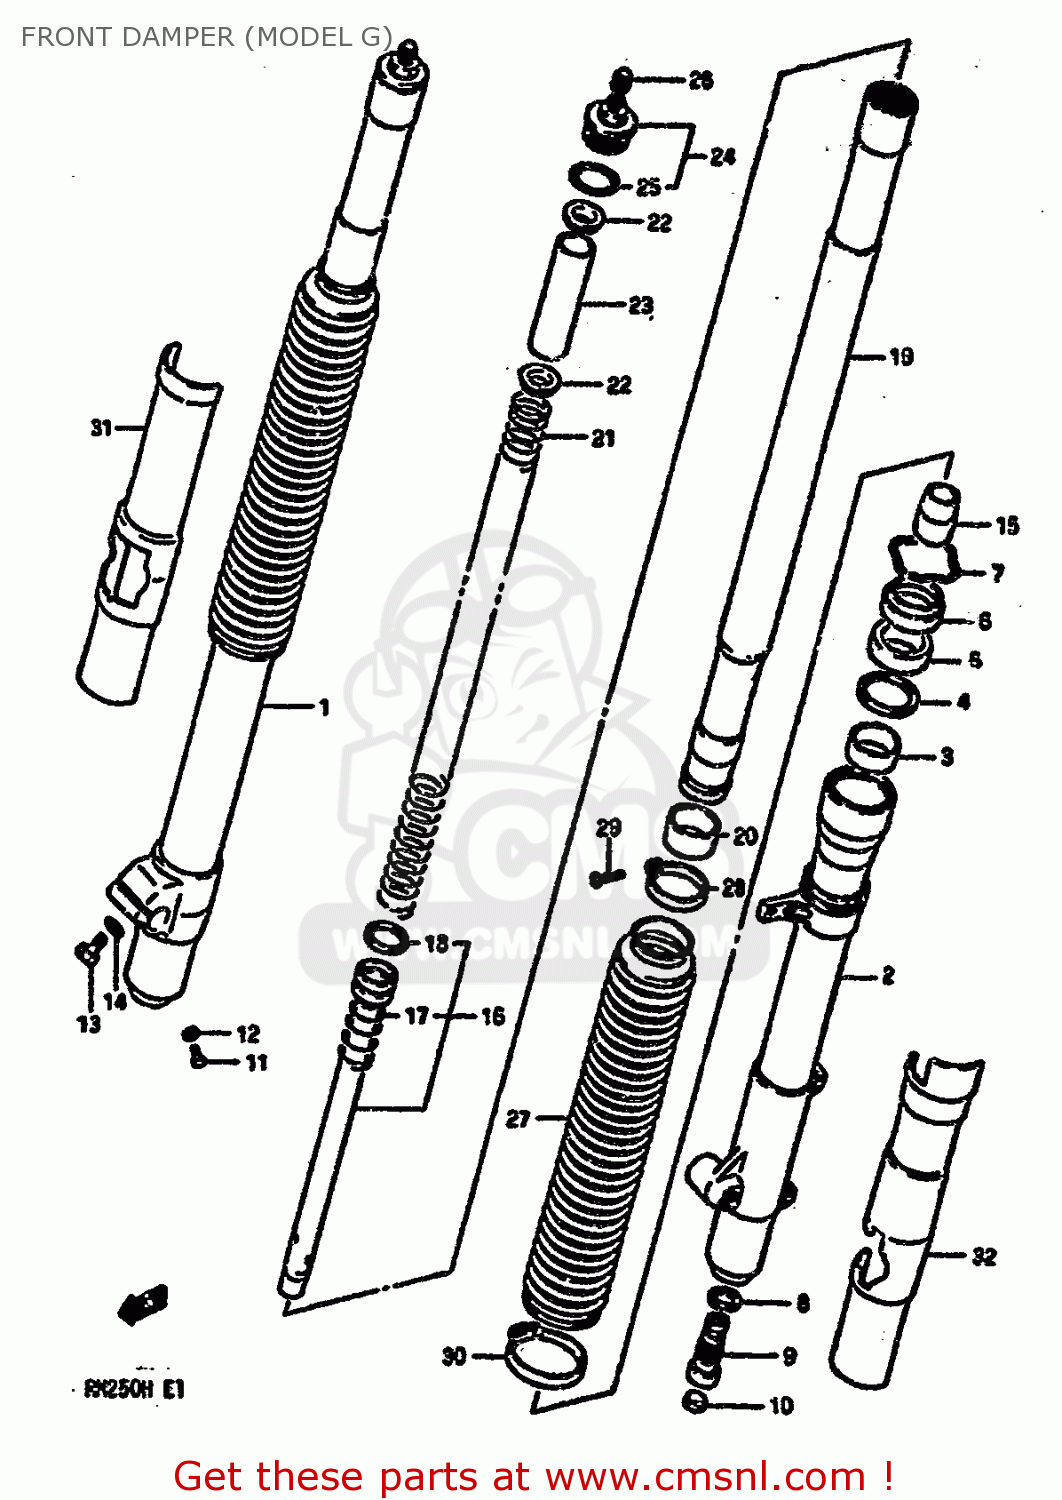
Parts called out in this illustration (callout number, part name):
1	TUBE,OUTER,RIGHT
2	TUBE,OUTER,LEFT
3	METAL,SLIDE
4	WASHER
5	SEAL,OIL
6	SEAL,DUST
7	RING,STOPPER
8	GASKET,FORK CYLINDER
9	VALVE,DF
10	CAP,FRONT FORK DF
11	SCREW 4X6
12	GASKET,DRAIN,PLUG (NAS)
13	BOLT
14	WASHER,LOCK,8.
15	PIECE,FRONT FORK OIL LOCK
16	CYLINDER,FRONT FORK
17	SPRING,REBOUND
18	RING,FRONT FORK PISTON
19	TUBE,FORK,INNER
20	PISTON
21	SPRING,FRONT FORK
22	GUIDE,FRONT FORK SPRING
23	SPACER,FRONT FORK SPRING
24	CAP,FORK INNER TUBE
25	O RING
26	CAP
27	BOOT
28	BAND,BOOT,UPPER
29	SCREW 4X10
30	BAND,BOOT LWR
31	PROTECTOR,RIGHT
32	PROTECTOR,LEFT
